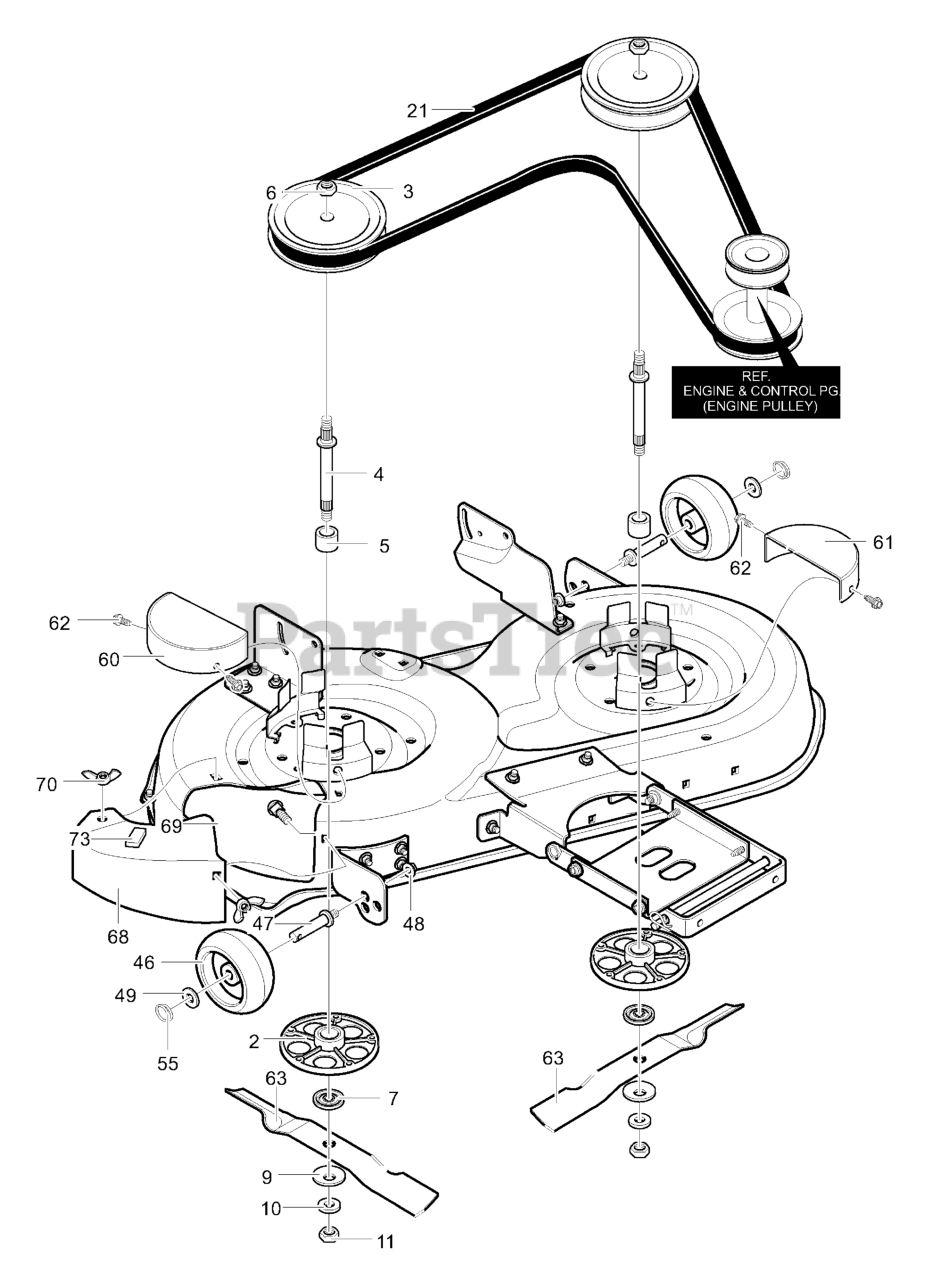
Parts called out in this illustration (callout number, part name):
2	HOUSING, JACKSHAFT
4	JACKSHAFT
6	NUT, 9/16-18
7	ADAPTER, BLADE
46	WHEEL, GAUGE
48	NUT,3/8-16
55	PIN, CIRCLE
60	GUARD, Belt R.H.
61	GUARD, Pulley L.H.
62	SCREW
63	BLADE
68	COVER, DISCHARGE
69	BOLT
70	NUT, WING
73	PAD, ADHESIVE
